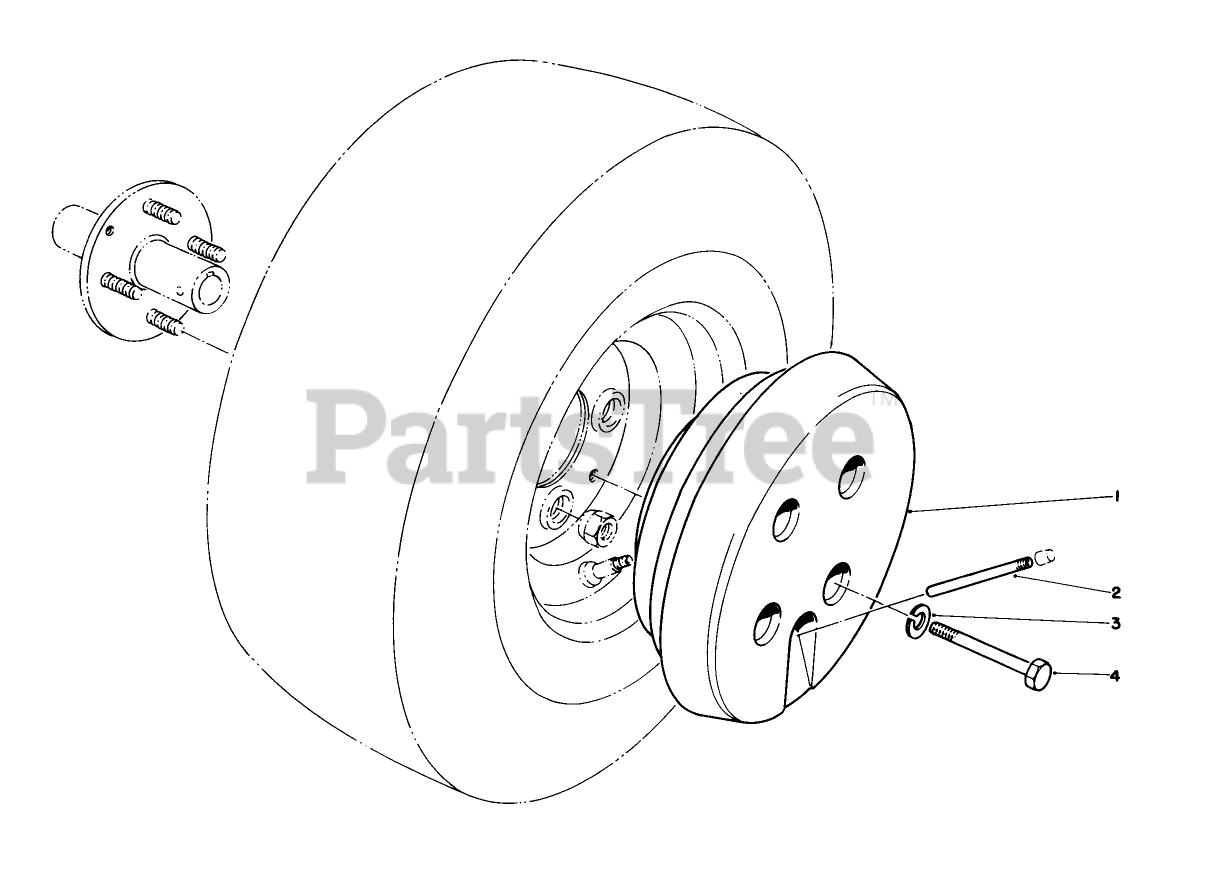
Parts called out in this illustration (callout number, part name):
2	VALVE EXTENSION
3	WASHER-LOCK
4	SCREW-HH
